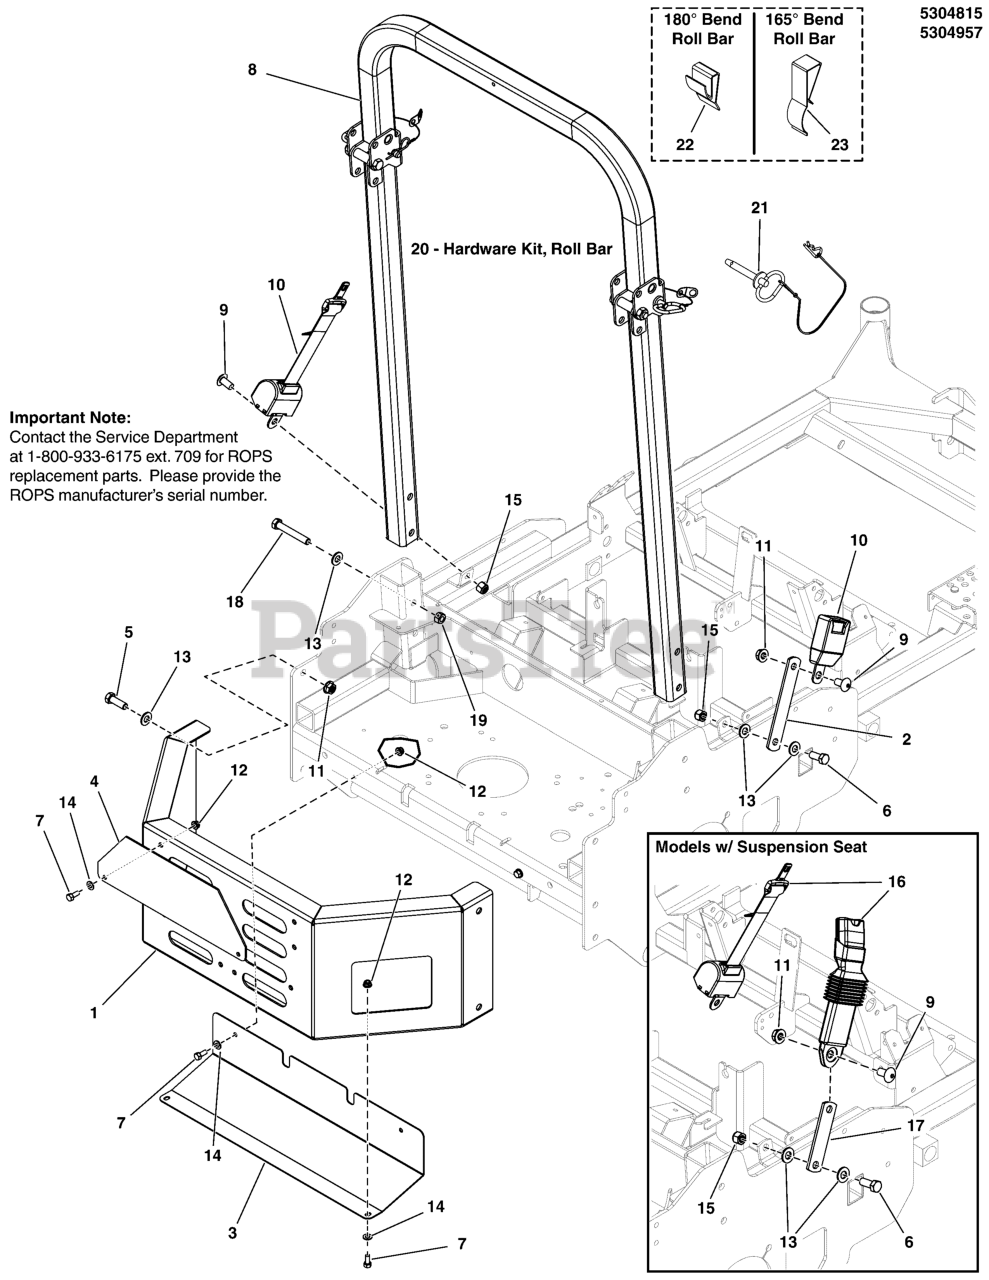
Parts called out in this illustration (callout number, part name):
1	WELD, REAR BUMPER,S200XT - RED
2	BAR, MOUNT, SEAT BELT, IS700Z - BLK
3	PLATE, HEAT SHIELD - BLK
4	PLATE, REAR BUMPER, 61 SNP - SNP RED
5	BOLT, 1/2-13 X 1-1/2 GD5 CZ
6	BOLT, 1/2-13 X 1-1/4 GD5 CZ
7	BOLT, 5/16-18 X 3/4 GD5
8	ROPS, S200XT & F320
9	SCREW, 1/2-13 X 1.00, SHCS
10	SEAT BELT, RETRACTING - ASSM
11	NUT, Hex Flange, Nylock, 1/2-13
12	NUT, 5/16-18 HEX NYLOCK FLANGE
13	WASHER, 1/2 SAE
14	WASHER, 5/16" SAE
15	NUT, 1/2-13 HEX NYLON LOCK
16	SEAT BELT ASSM, RETRACTOR + SUP SLEEVE
17	EXTENSION, SEAT BELT - BLK
18	BOLT, 1/2-13 X 3-1/4, HEX HD, GD5, CZ (SV)
19	NUT, 1/2-13 HEX SIDE LOCK
20	HARDWARE KIT, ROLL BAR
21	PIN, HITCH, .50 X 3.25 W/ LAY
22	ANTI-RATTLE SPRING, FEMCO #230328972 (SV)
23	ANTI-RATTLE SPRING, ROPS, 165 DEGREE (SV)
